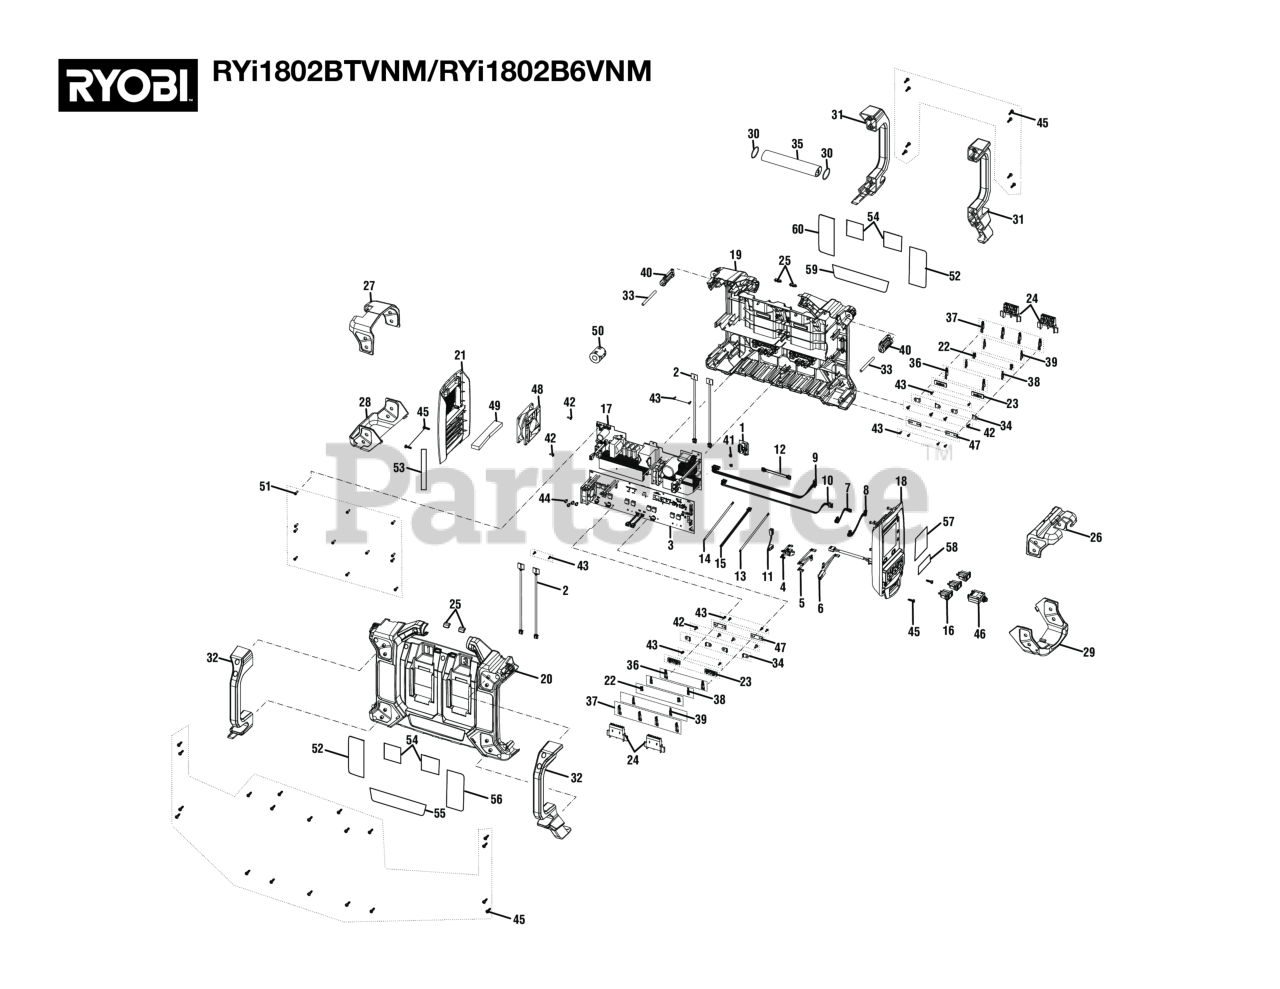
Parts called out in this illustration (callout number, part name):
1	Program Circuit Board Assembly
2	LED Circuit Board Assembly
3	Main Circuit Board Assembly
4	Output Assembly
5	Harness Circuit Breaker to Receptacle
6	Harness Parallel to Circuit Breaker
7	Controller Harness
8	Firmware Harness
9	Inverter Harness
10	Inverter to Controller Harness
11	BMS to Controller Harness
12	PH-5Y Female Harness
13	Negative Battery Cable
14	Positive Battery Cable.
15	Battery Harness
16	120V Power Outlet Receptacle
17	1600W Inverter Circuit Board Assembly
18	Front Cover Assembly (Inc. Key Nos. 57-58)
19	Housing Cover (Right, Inc. Key Nos. 52, 54 & 59-60)
20	Housing Cover (Left, Inc. Key Nos. 52 & 54-56)
21	Rear Housing Cover (Inc. Key No. 53)
22	Contact Holder
23	Battery Cover Connector
24	Battery Contact Holder
25	LED Light Lens
26	Top Bumper (Front)
27	Top Bumper (Rear)
28	Bottom Bumper (Rear)
29	Bottom Bumper (Front)
31	Handle (Right)
32	Handle (Left)
33	Strap Pin
34	Brush Skirt Clip
35	Handle Tube
36	STAMPING I BATTERY CONTACT PLATE TERMINA
37	Contact Plate Terminal
38	T2 Contact Strip (Upper)
39	T2 Contact Strip (Lower)
40	Strap Retainer
41	SCREW (M2.3 X 6 mm)
42	Screw (M3 x 10 mm)
43	Screw (M3 x 8 mm, Pan Hd., Pan Hd)
44	Screw (M4 x 16 mm, Pan Hd.)
45	Screw (M4.2 x 15 mm, Phillips Hd. S.T.)
46	15A Circuit Breaker
47	Battery Connector Cover
50	Magnet Ring
51	Screw (M3.5 x 12 mm, T15 Torx Pan Hd.)
52	Charging Indicator Label
53	FCC Label
54	Battery Callout Label
55	RYOBI/Power Station Logo Label
56	Warning Label
57	Main Power label
58	Logo Label
59	Battery Warning Label
60	Data Label
